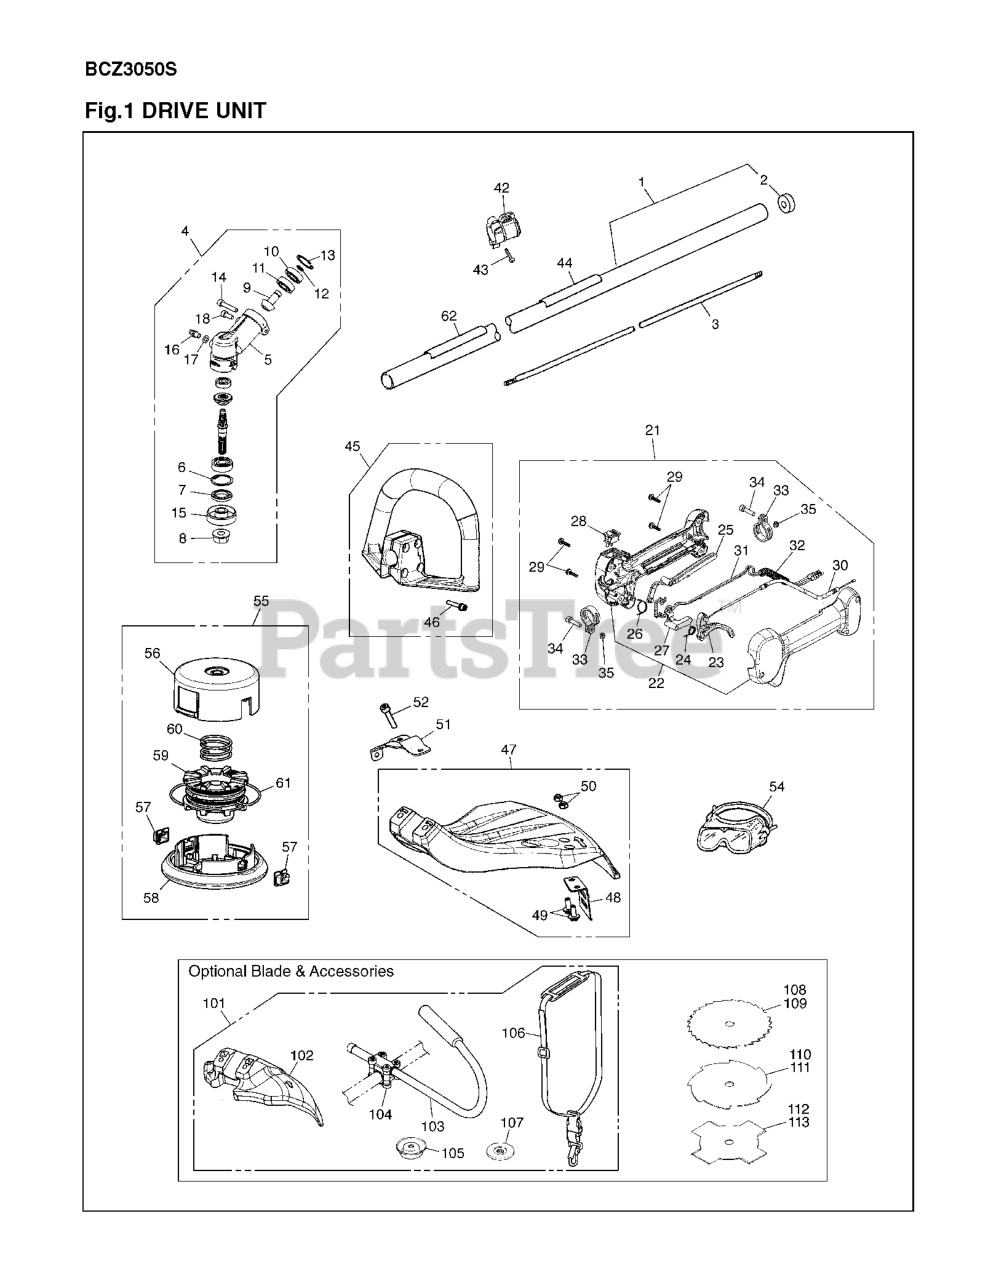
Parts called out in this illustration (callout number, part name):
1	PIPE COMP
3	SHAFT (RPLS -12212,936612210)
4	GRIP-A
5	%LEVER SAFETY
6	RING,SNAP M26x1.2 RP-318013340
7	SEAL, OIL(RPLS 3565-13131)
11	BALL BEARING
13	RP_RING
14	BOLT, TORX
15	HOLDER (A)
16	FITTING, GREASE
18	BOLT, TORX
21	CORD - C
23	LEVER, THROTTLE
24	SPRING, THROTTLE
25	LEVER FOR GRIP (RPLS -0600)
26	SPRING JOINT
27	LEVER JOINT
31	CORD - C
34	SCREW
35	NUT
42	HANGER COMP.
43	SCREW
45	HANDLE ASSY. (RPLS T319514001)
46	SCREW
47	GUARD ASSY
49	SCREW
52	BOLT, TORX
54	GOGGLExxx (RPLS
56	CASE (RPL T318915112)
57	EYELET
58	COVER (RPLS T318915131)
59	HOLDER, CORD (RPLS T318915141)
61	CORD
62	LABEL CAUTON FOR BC
101	BLADE KIT BCZ 24/26/30 SERIES
103	J-HANDLE
104	BRACKET ASSY.
105	COVER(10mm)(RPL280,-13280)
106	STRAP ASSY
107	HOLDER (B)
108	Brushcutter Blade, 22 Tooth 9"
109	Brushcutter Blade, 24 Tooth 9"
110	BLADE, 8
111	Brushcutter Blade, 8 Tooth 9"
112	BLADE, 8
113	Brushcutter Blade, 4 Tooth 9"
